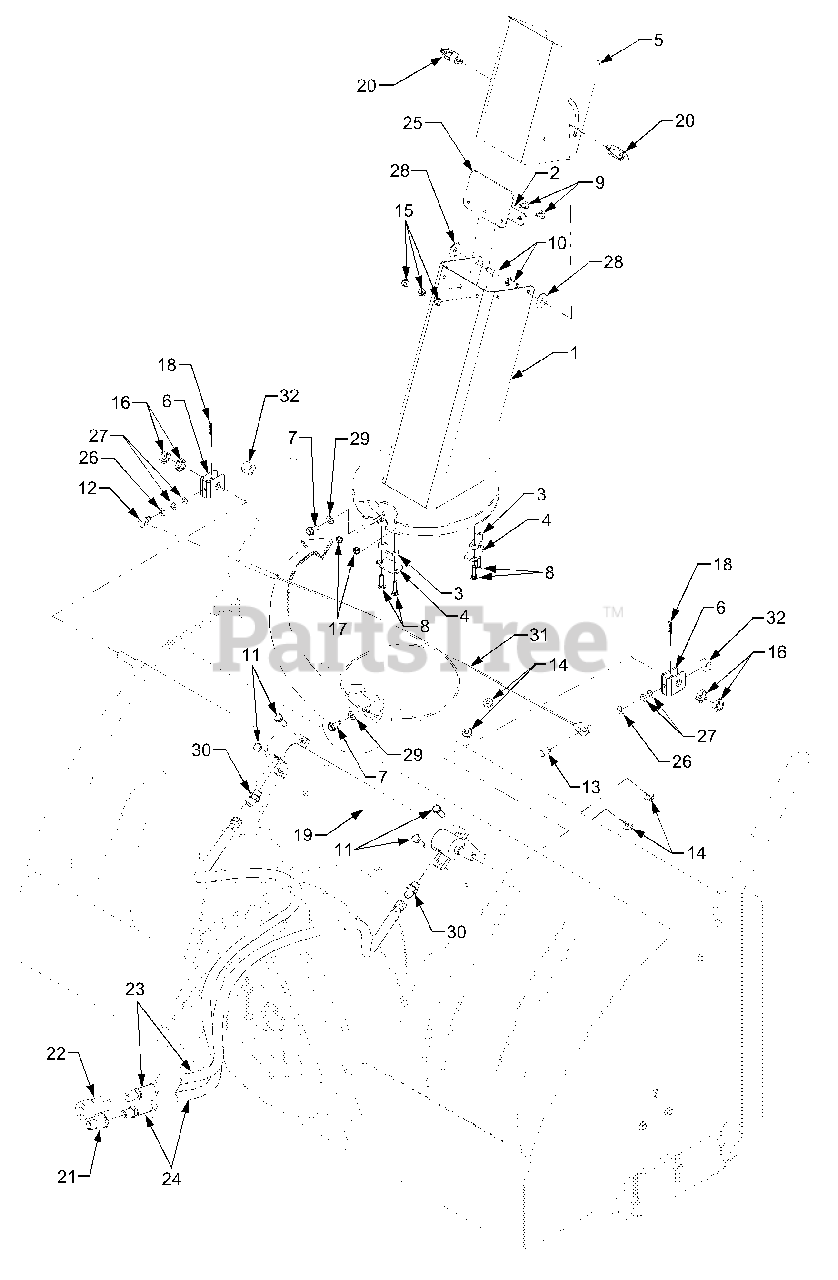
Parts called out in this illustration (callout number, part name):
1	Chute, Discharge
2	Bracket, Rubber Deflector
5	Deflector, Chute
6	Bracket, Rod End
7	Screw, Hex Wash. Hd. Tapp 5/16-18 x .75
8	Screw, Carriage, 1/4-20 x 1.0
9	Screw, Truss Hd., 1/4-20 x .625
10	Bolt, Carriage, 5/16-18 x 7/8
11	Screw, Hex Cap Lock 3/8-16 x 1.0 GR5
12	Ferrule, 5/16-18 x .312 Dia
13	Pin, Clevis, .312 x 1.0
14	Nut, Hex Flange Lock, 3/8-16
15	Nut, Hex Flange Lock, 1/4-20
16	Nut, Hex Jam, 9/16-18 GR5
17	Nut, Hex Nylon Lock, 1/4-20 GR8
18	Pin, Internal Cotter
19	Cylinder, Chute
20	Knob, Wing Nut, 5/6-18
21	Coupling, Hydraulic - Male
22	Coupling, Hydraulic - Female
23	Hose, Hydraulic, 3/8 ID x 62"
24	Hose, Hydraulic, 3/8 ID x 82"
25	Deflector, Rubber
26	Washer, Flat, .33 x .63 x .0635
27	Washer, Spring, .317 x .625
28	Washer, Flat, .348 x 1.16 x .064
29	Washer, Flat, .344 x .688 x .065
30	Fitting, Straight Hydraulic
31	Cable, Chute Rotation
32	Spacer, .56 ID x .81 OD x .66
